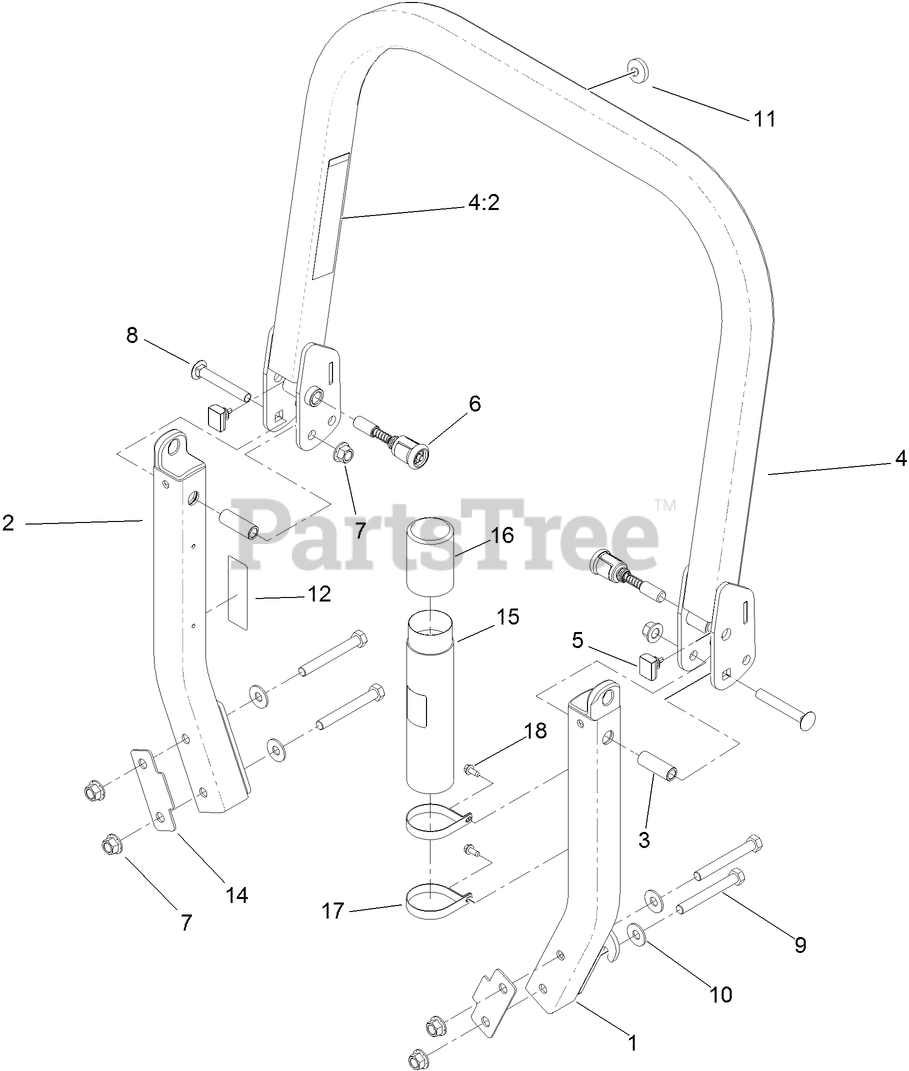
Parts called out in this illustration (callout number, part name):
1	LEG-ROPS, LH
2	LEG-ROPS, RH
3	SPACER
4	UPPER ROPS ASM
4:2	DECAL-WARNING, FOLDING ROPS
5	BUMPER-ROPS
6	PIN-SPRING
7	NUT-LOCK
8	SCREW-CARR
9	SCREW-HH
10	WASHER-SPRING
11	BUMPER-PUSH-IN, RUBBER
12	DECAL-CAUTION
14	SPACER
15	TUBE-MANUAL
16	CAP-HOUSING
17	R-Clamp
18	SCREW-HWH
